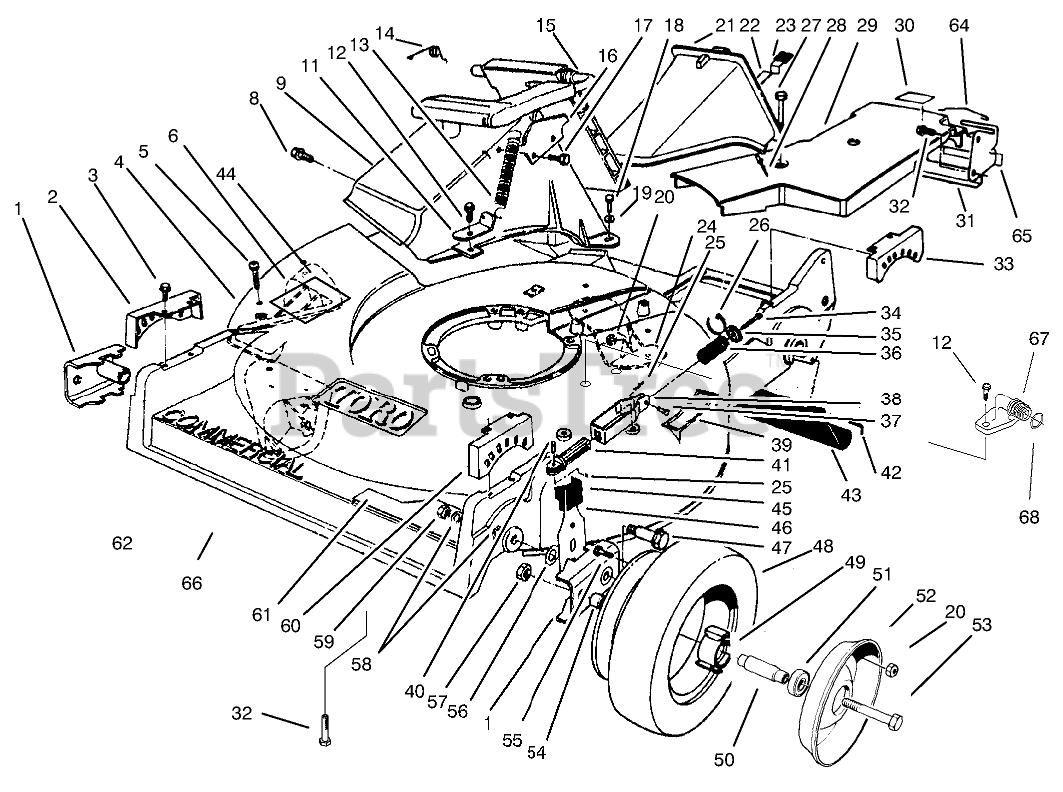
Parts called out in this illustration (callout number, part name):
1	ARM-PIVOT, FRONT
2	QUADRANT-FRONT, RH
3	SCREW-HWHTF
4	Housing-Commercial (Incl. Ref. #5, 6, 12, 24, 32, 44, 62, & 66-68)(Incl. Ref. #28 pg. 4)
5	SCREW-PPH
6	KICKER-RH
8	SCREW AND WASHER ASM
9	TUNNEL-DISCHARGE
11	BRACKET-SPRING
12	SCREW-HWH
13	SPRING-DOOR
14	RETAINER-DOOR
15	DOOR ASSEMBLY
16	DOOR LATCH PLATE
17	SCREW-PLASTITE
18	SCREW-HH
19	WASHER-FLAT
20	NUT-LOCK, NI
21	Plug-Discharge (Incl. Ref. #22, 23, & 28)
22	LATCH-PLUG, DISCHARGE
23	GRIP-LATCH
24	KICKER-REAR
25	PIN-COTTER
26	TIE-CABLE
27	SCREW-HHFTF
28	RIVET-HEAD, FLAT
29	BELT COVER
30	DECAL-GREASE
31	BRACKET-ADJUSTMENT, TRACTION
32	SCREW-HWHTF
33	QUADRANT-REAR, LH
34	SCREW-HWHTF
35	RETAINER-SPRING
36	SPRING
37	PIN-CABLE
38	Bracket-Spring
39	DECAL - STEP PAD INT'L
40	PIN-SPRING
41	GUIDE-SPRING
42	ROD-SHIELD
43	SHIELD-TRAILING
44	DECAL-DANGER
45	KNOB-ARM
46	FRONT SPRING ARM ASM
47	BOLT-WHEEL
49	HUB-BEARING
50	SPACER-BEARING
51	BEARING-WHEEL
52	Wheel-Half
53	SCREW-HH
54	SPACER-WHEEL
55	SCREW-HH
56	WASHER-THRUST
57	NUT-LOCK, CONE
58	WASHER
59	NUT-LOCK
60	QUADRANT-FRONT, LH
61	DECAL - DECK
62	KICKER-FRONT
64	RETAINER-CABLE
65	DECAL-POSITION, GEAR
66	Shield-front
67	FITTING-WASHOUT
68	O-RING
